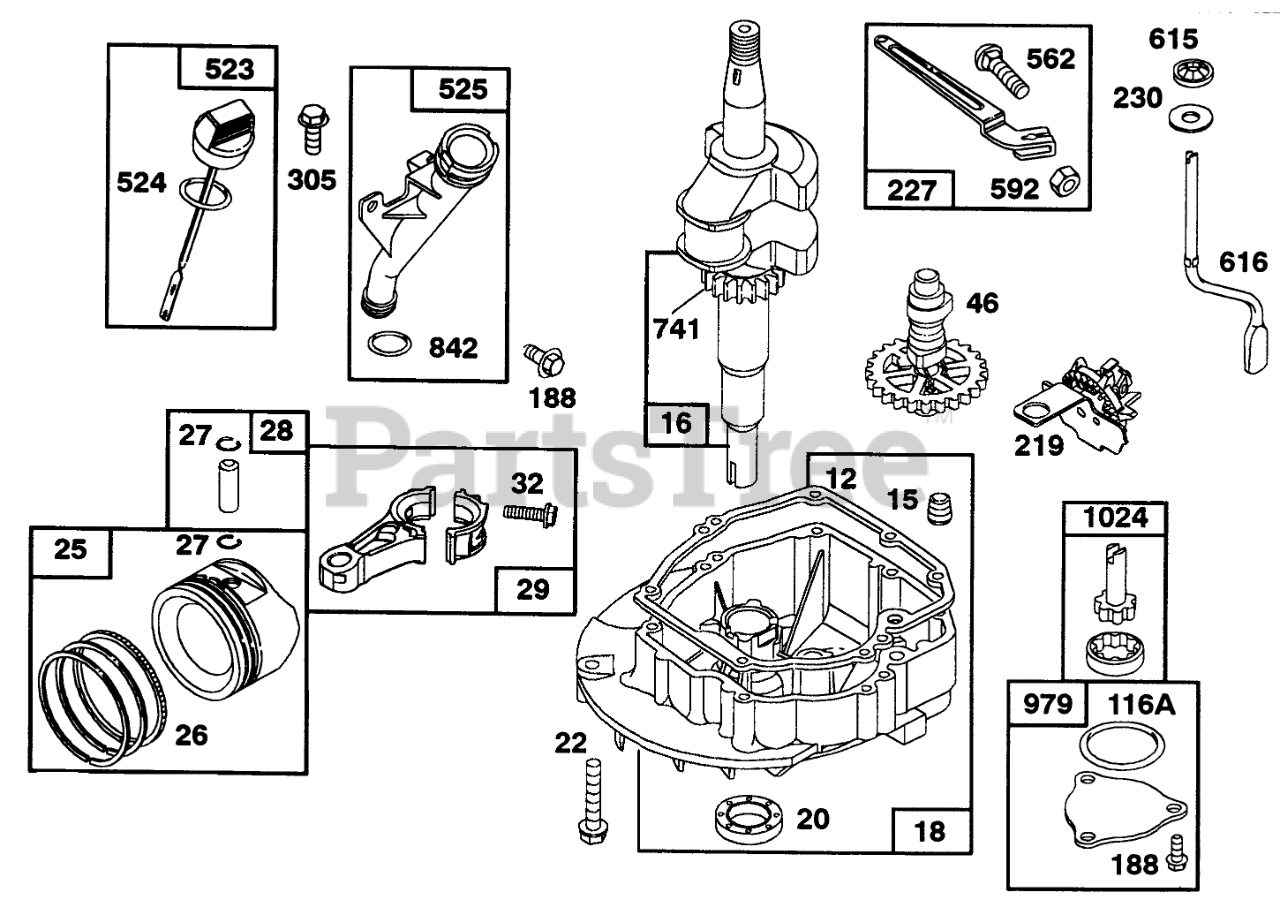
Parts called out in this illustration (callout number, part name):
12	ENGINE BASE GASKET
15	PLUG - OIL DRAIN
16	CRANKSHAFT
18	ENGINE SUMP
20	SEAL-OIL
22	SCREW - ENGINE BASE
25	STD PISTON ASSEMBLY
26	STD RING SET
27	PISTON PIN LOCK
28	Pin Assy-Piston
29	CONNECTING ROD
32	Connecting Rod
46	CAM GEAR
116A	O RING SEAL
188	SCREW - SEM
219	GOVERNOR/OIL SLINGER
227	GOVERNOR LEVER ASSEMBLY
230	WASHER
305	SCREW - HEX HEAD
523	DIPSTICK-OIL
524	O-RING
525	OIL FILLER TUBE
562	GOVERNOR LEVER BOLT
592	HEX NUT
615	FASTENER
616	GOVERNOR CRANK
741	TIMING GEAR
842	O-RING
979	OIL PUMP COVER
1024	OIL PUMP
